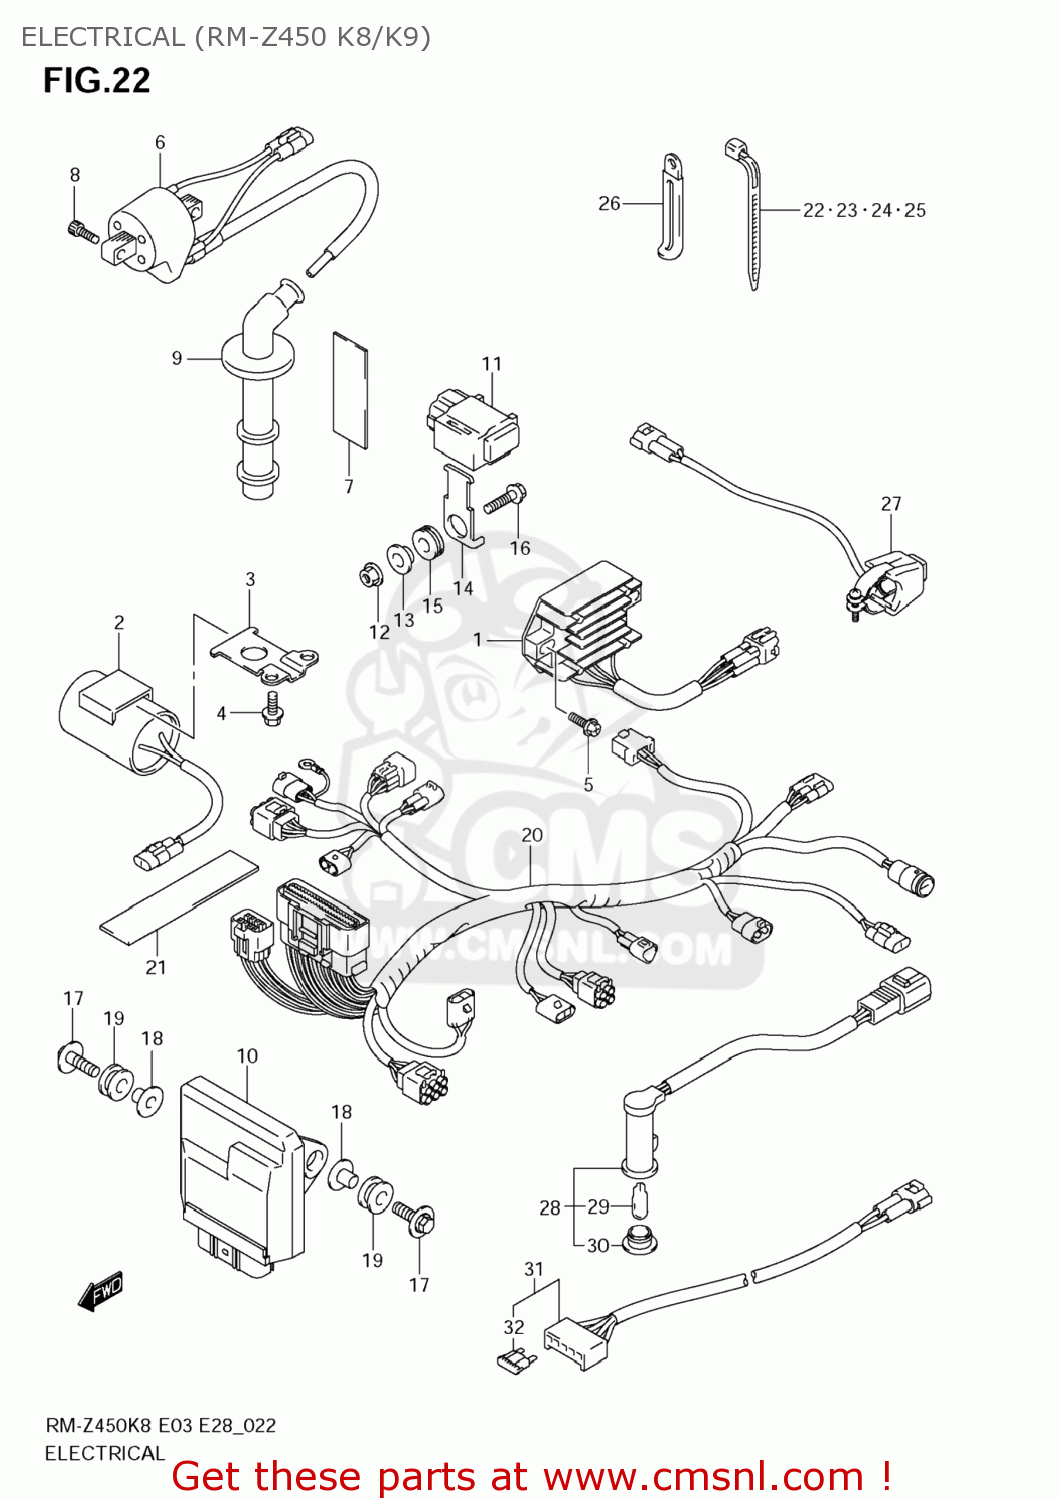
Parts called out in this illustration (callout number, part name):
1	RECTIFIER ASSY
2	CONDENSER ASSY
3	BRACKET,CONDENSER
4	BOLT(6X10)
5	SCREW
6	COIL ASSY,IGNITION
7	PROTECTOR(30X80X1)
8	BOLT
9	CAP ASSY,SPARK PLUG
10	CONTROL UNIT,FI
11	SENSOR ASSY,FUEL CUT
12	NUT
13	SPACER(6.2X8.4X10.9)
14	BRACKET,FUEL C
15	CUSHION
16	BOLT
17	BOLT(6X20)
18	SPACER(6.2X8.4X10.9)
19	GROMMET
20	HARNESS,WIRING
21	PROTECTOR(20X90)X1.0
22	CLAMP(L:95)
23	CLAMP(L:125)
24	CLAMP(L:165)
25	CLAMP(L:235)
26	CLAMP(L:45)
27	SWITCH ASSY,ENGINE STOP
28	LAMP ASSY,FI INDICATOR
29	BULB(12V3.4W,T10)
30	LENS(RED)
31	WIRE,BATTERY
32	FUSE(10A)
